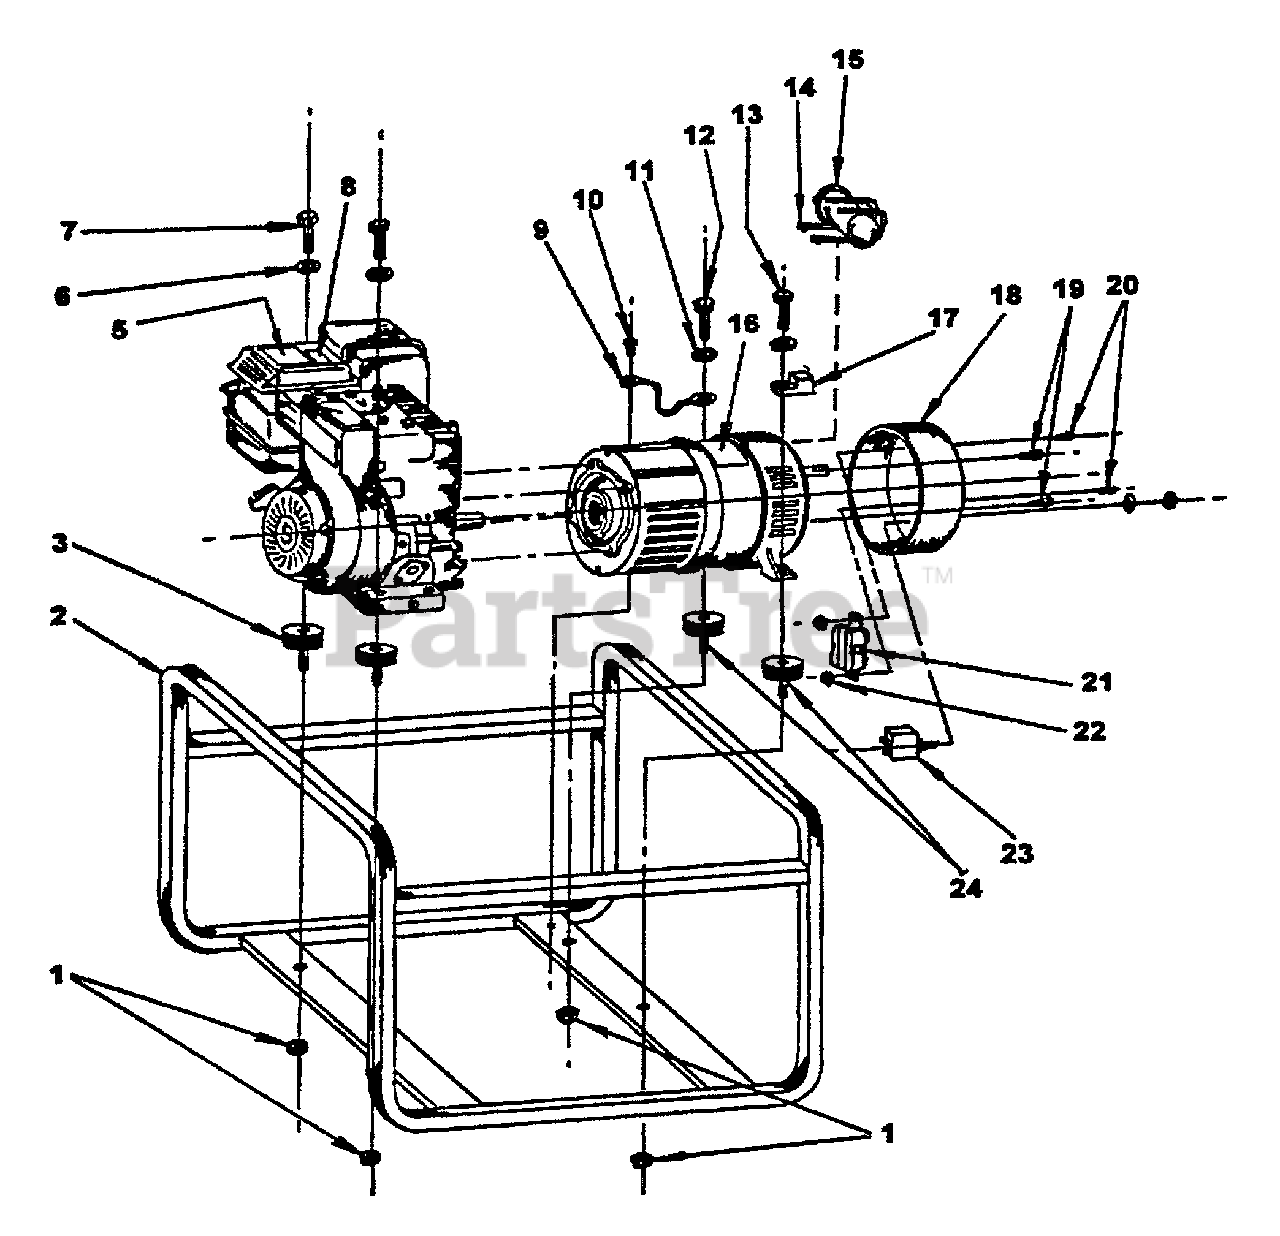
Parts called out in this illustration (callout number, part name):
1	LOCKNUT - 5/16-18
2	FRAME
3	ISOLATOR, VIBRATION
5	LABEL - SAFETY
6	LOCKWASHER - 5/16"
7	BOLT - 5/16-18 X 1-1/2"
9	LEAD - GROUND
10	SCREW - 10-24
11	LOCKWASHER - 5/16"
12	5/16-18X5/8 HHS
13	5/16-18X7/8 HHS
14	TIE, CABLE
15	CAPACITOR - 50UF 370V
16	LABEL - MODEL EG-1800
17	LUG, GROUND - 1/0-14 CU/AL
18	PANEL, END
19	SCREW - 10-24
20	8-32X3/8 RHS
21	DUPLEX, 15A/125V
22	NUT - 8-32 -- KEPS
23	BREAKER, CIRCUIT - 15A/250V
24	ISOLATOR, VIBRATION
